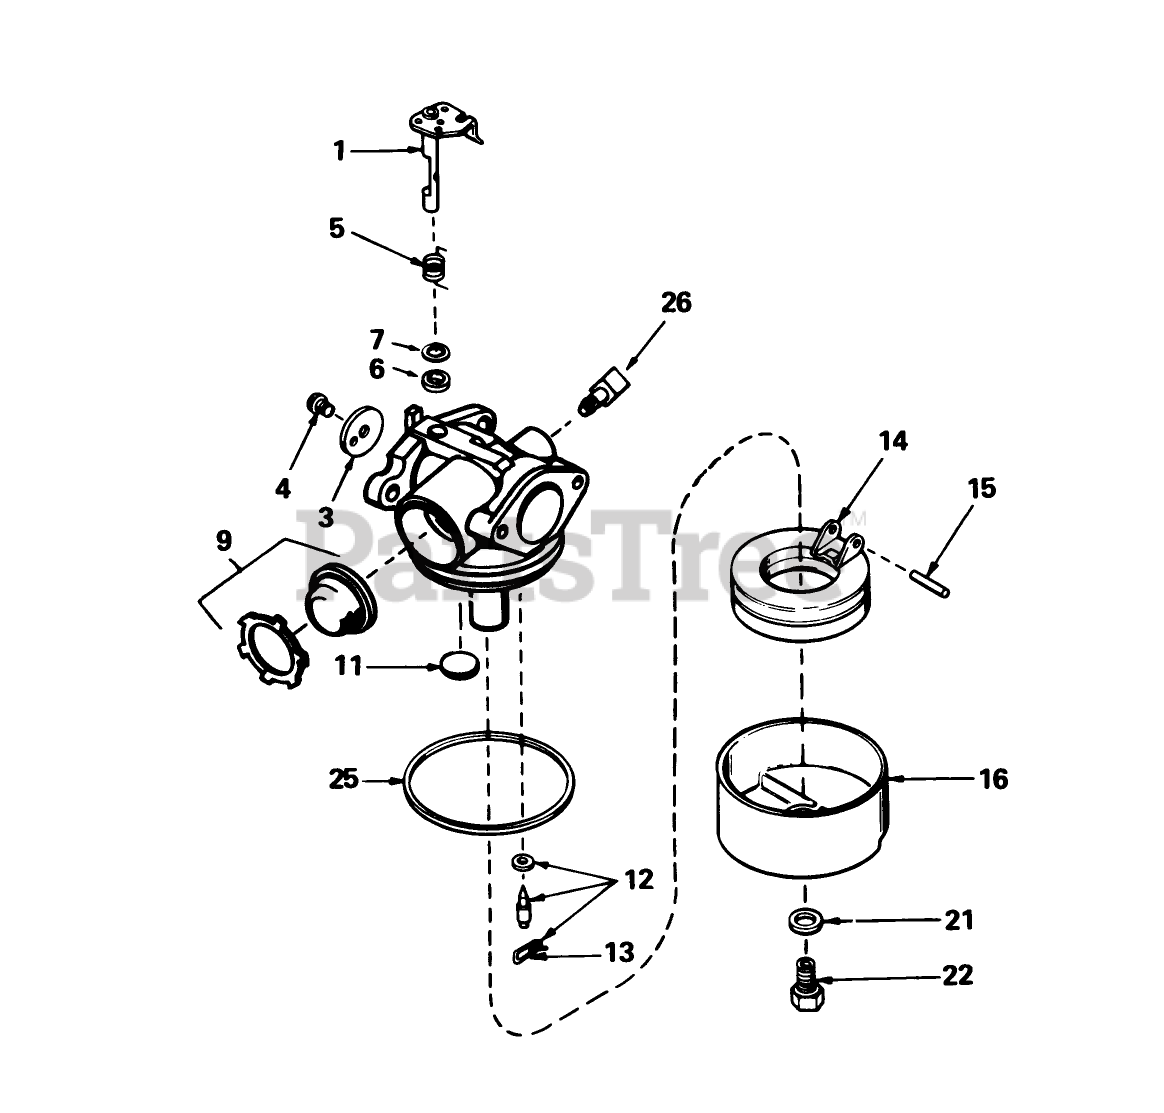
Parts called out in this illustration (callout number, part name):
1	Throttle Shaft and Lever ASM
3	Throttle-Shutter
4	Screw-Shutter
5	Spring-Return, Throttle
6	Seal-Dust
7	Washer-Seal, Dust
9	Primer Assy.
11	Plug-Welch, Atmospheric Vent
12	Inlet Needle, Seat Clip Assy. (Incl. No. 13)
13	Clip-Spring
14	Float
15	Shaft-Float
16	Bowl Float
21	Gasket-Bowl
22	Nut-Float Bowl
25	O Ring-Bowl, Float
26	Fitting-Fuel
